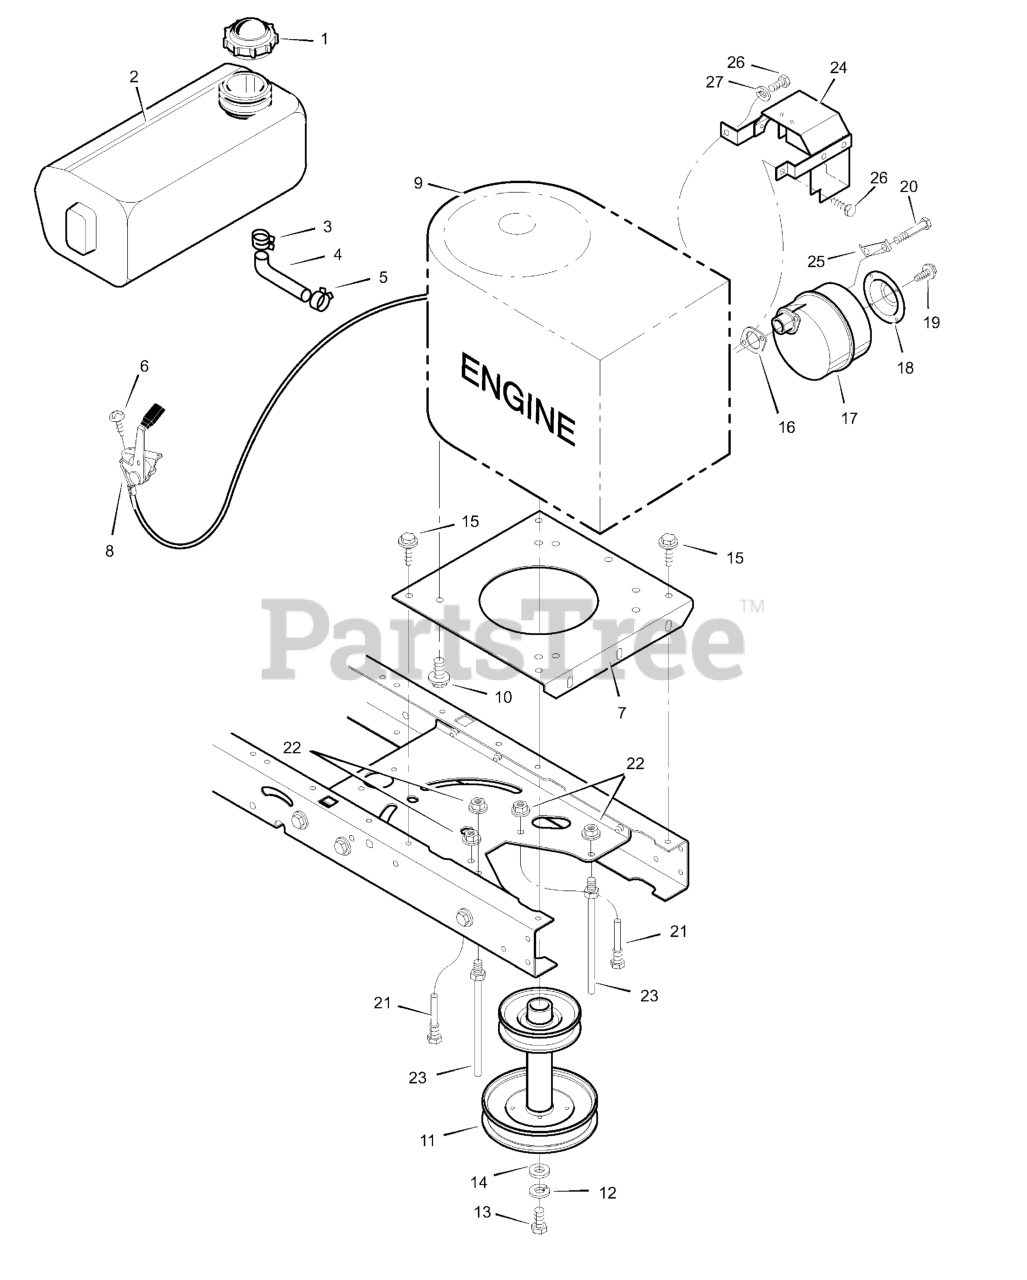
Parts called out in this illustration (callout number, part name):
1	Fuel Cap
2	Fuel Tank
3	Hose Clamp
4	Fuel Line
5	Hose Clamp
7	Plate, Engine
8	Throttle Control
9	Engine *
10	Bolt, Engine Mount
11	STACK PULLEY ASSEMBLY
12	Lockwasher
13	Bolt, Hex
16	GASKET, Exhaust
17	Muffler
18	Deflector, Muffler
20	Bolt, Hex
21	Guide, Belt
22	Nut, Flange
23	Guide, Belt
24	Shield, Heat
25	Lock, Screw
